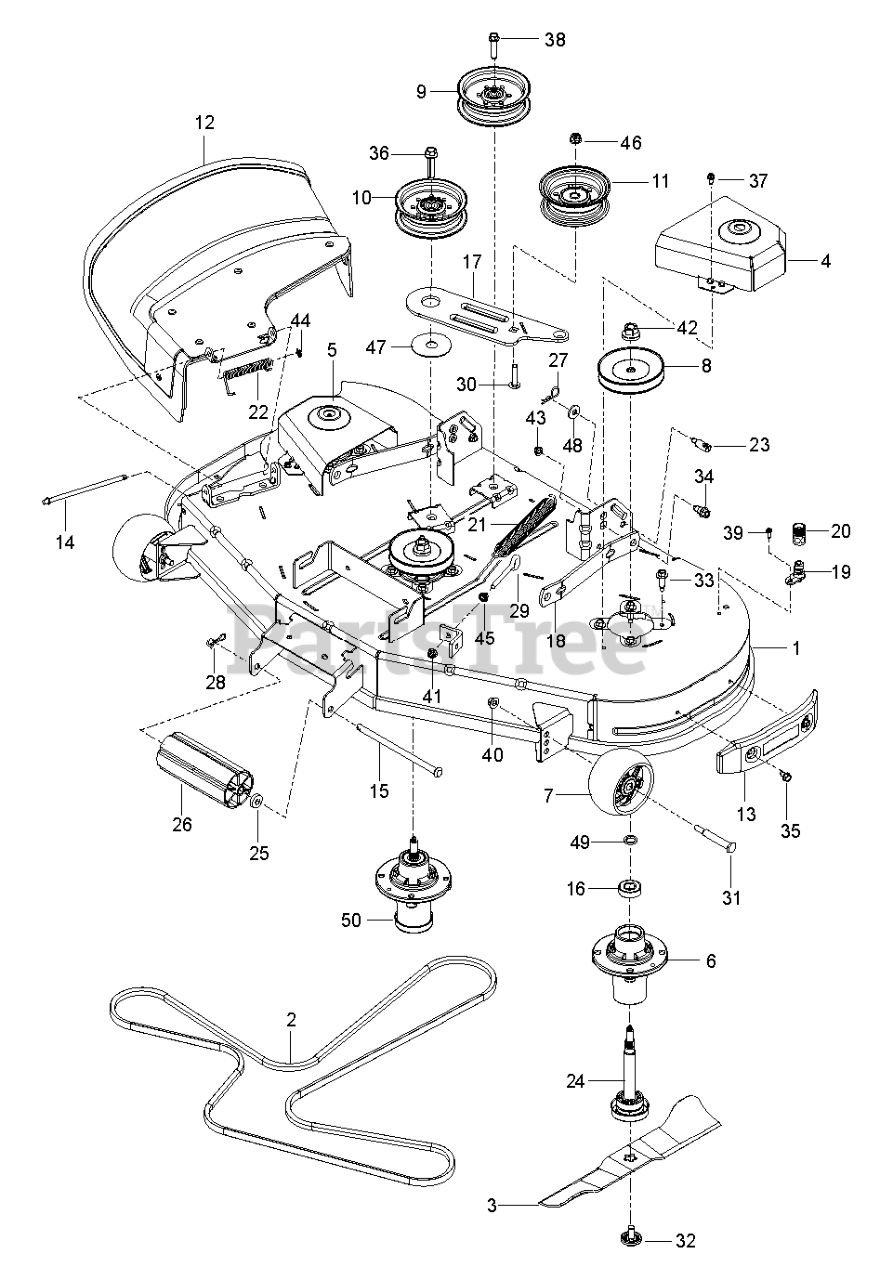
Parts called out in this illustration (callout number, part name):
1	KIT.SVC.48.CC.RZ.DSHLL.ASM.668
3	BLADE.BAGGER.RES.CLRCT.48".BLK
4	COVER.PNT.MANDREL.LH.ZTR.GREY
5	COVER.PNT.MANDREL.RH.GREY
6	MANDREL, HOUSING - CAST IRON
7	WHEEL.GAUGE.RALLY
8	MANDREL.PULLEY.38.BRIGHT.ZINC
9	PULLEY.IDLER.2006
10	PULLEY.IDLER.MWR.STATI.LH
11	PULLEY.IDLER.48"PRIMARY
12	DEFLECTOR.ASM.48".CLRCT.RES.OR
13	BUMPER.ASM.SIDE.TRIM.CLRCUT.48
14	ROD.HINGE
15	ROD.ROLLER.NOSE.NARROW.48"
17	ARM.PNT.CLUTCHING.EDIP
18	ARM.RFIXED.MOWER.SUSPNSIONX431
19	PORT.WASHOUT
20	COUPLING.QUICK CONNECT
21	SPRING.EXTENSION
22	SPRING.42.FCS.DEFLECTOR
23	STUD.FASTNER.W/ANTI-ROTATE
24	SHAFT ASM MANDREL
25	BUSHING.NOSE.ROLLER
26	NOSE ROLLER 48"
27	PIN.COTTER.7/16.BOW TI.
28	PIN.COTTER.5/16.BOW TI
29	EYE BOLT 5/16 X 3.50
31	BOLT.SHOULDER.3/8-16X3-5/8.
32	BOLT.WASHER.ASM.7/16-2
33	BOLT.HEX.WASHR.HED.313-18X1.19
34	BOLT.SHOULDER
35	SHOULDER BOLT 5/16-18TT
36	SCREW.7/16-14 X 2.125.WASHER
37	SCREW.1/4-20X5/8
38	SCREW LT
39	SCR 1/4-20X5/8 HEX SELF TAP ZD
40	NUT 3/8-16 HEX FLG NYLOC ZD
41	5/16-18 NYLOC FLANGE NUT
42	NUT.FLANGE.LOCK.TOP
43	NUT LOCK HEX FLANGE 5/16-18
44	NUT PUSH M
45	NUT 5/16C WHIZ
48	WASHER
49	WASHER.SPACER.MANDREL
50	MANDREL ASM, CAST IRON
